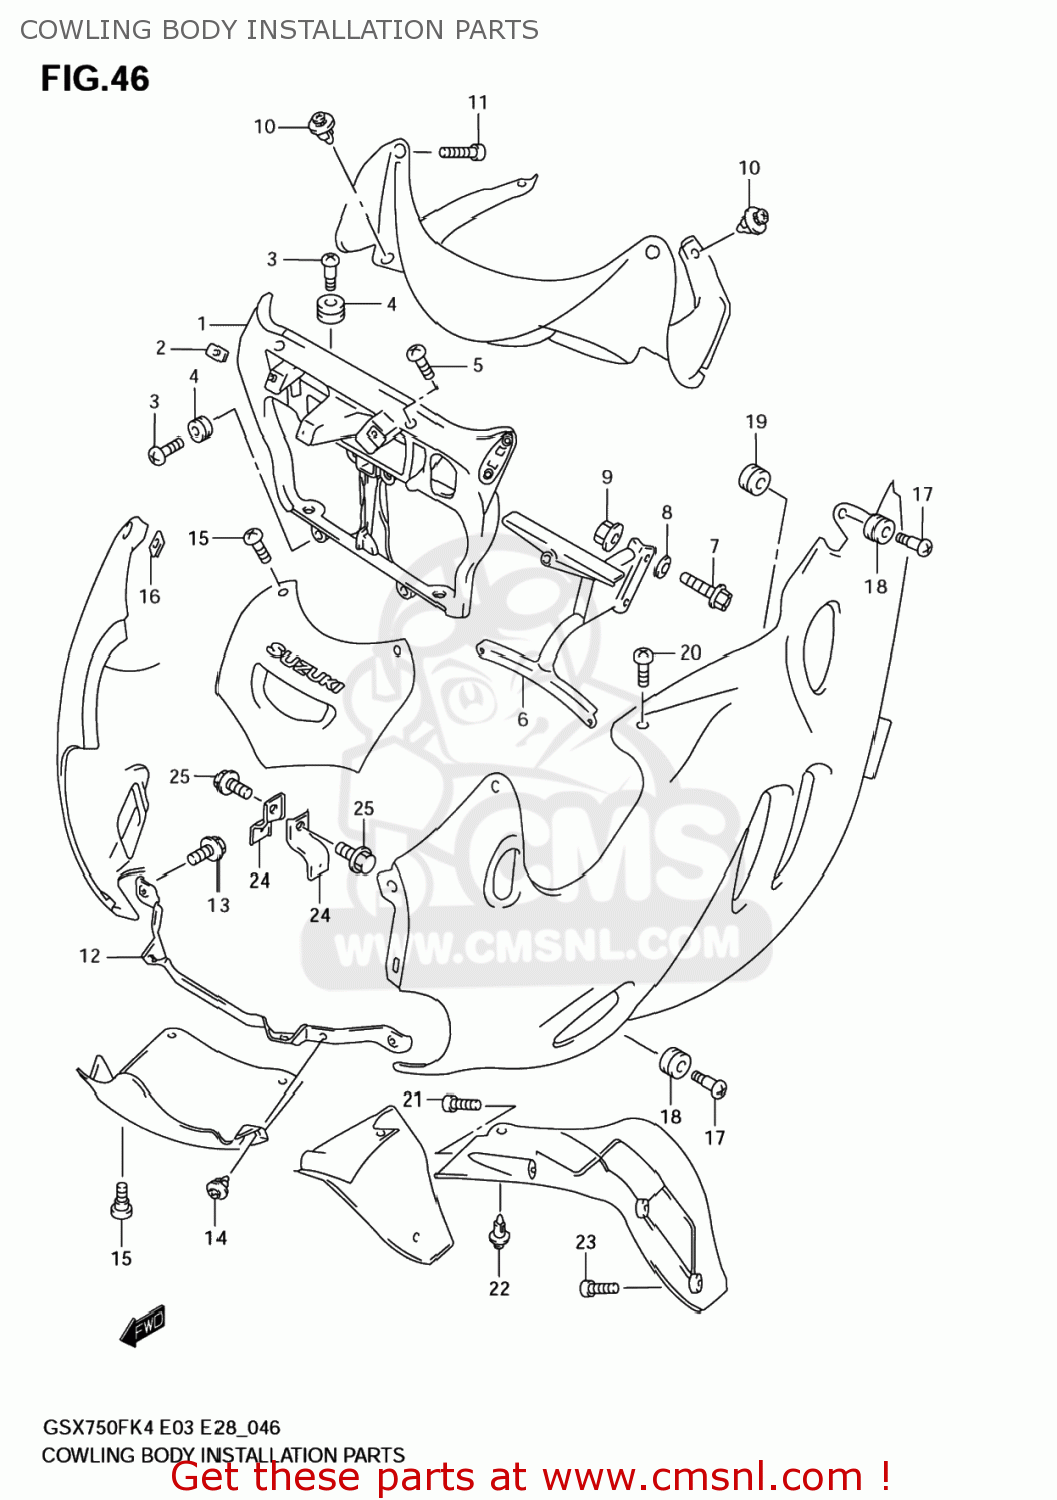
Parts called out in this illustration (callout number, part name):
1	BRACE,COWLING FR
2	NUT,COWL
3	SCREW(6X20)
4	CUSHION
5	SCREW
6	BRACE,COWLING RR
7	BOLT(8X40)
8	WASHER
9	NUT
10	CLIP(BLACK)
11	SCREW
12	BRACKET,PANEL CTR LWR
13	BOLT
14	CLIP(BLACK)
15	SCREW(5X16)
16	NUT
17	SCREW(6X20)
18	CUSHION
19	CUSHION
20	SCREW(5X16)
21	SCREW(4X10)
22	CLIP(BLACK)
23	SCREW
24	BRACKET,COWLING SIDE LWR
25	BOLT(6X12)
